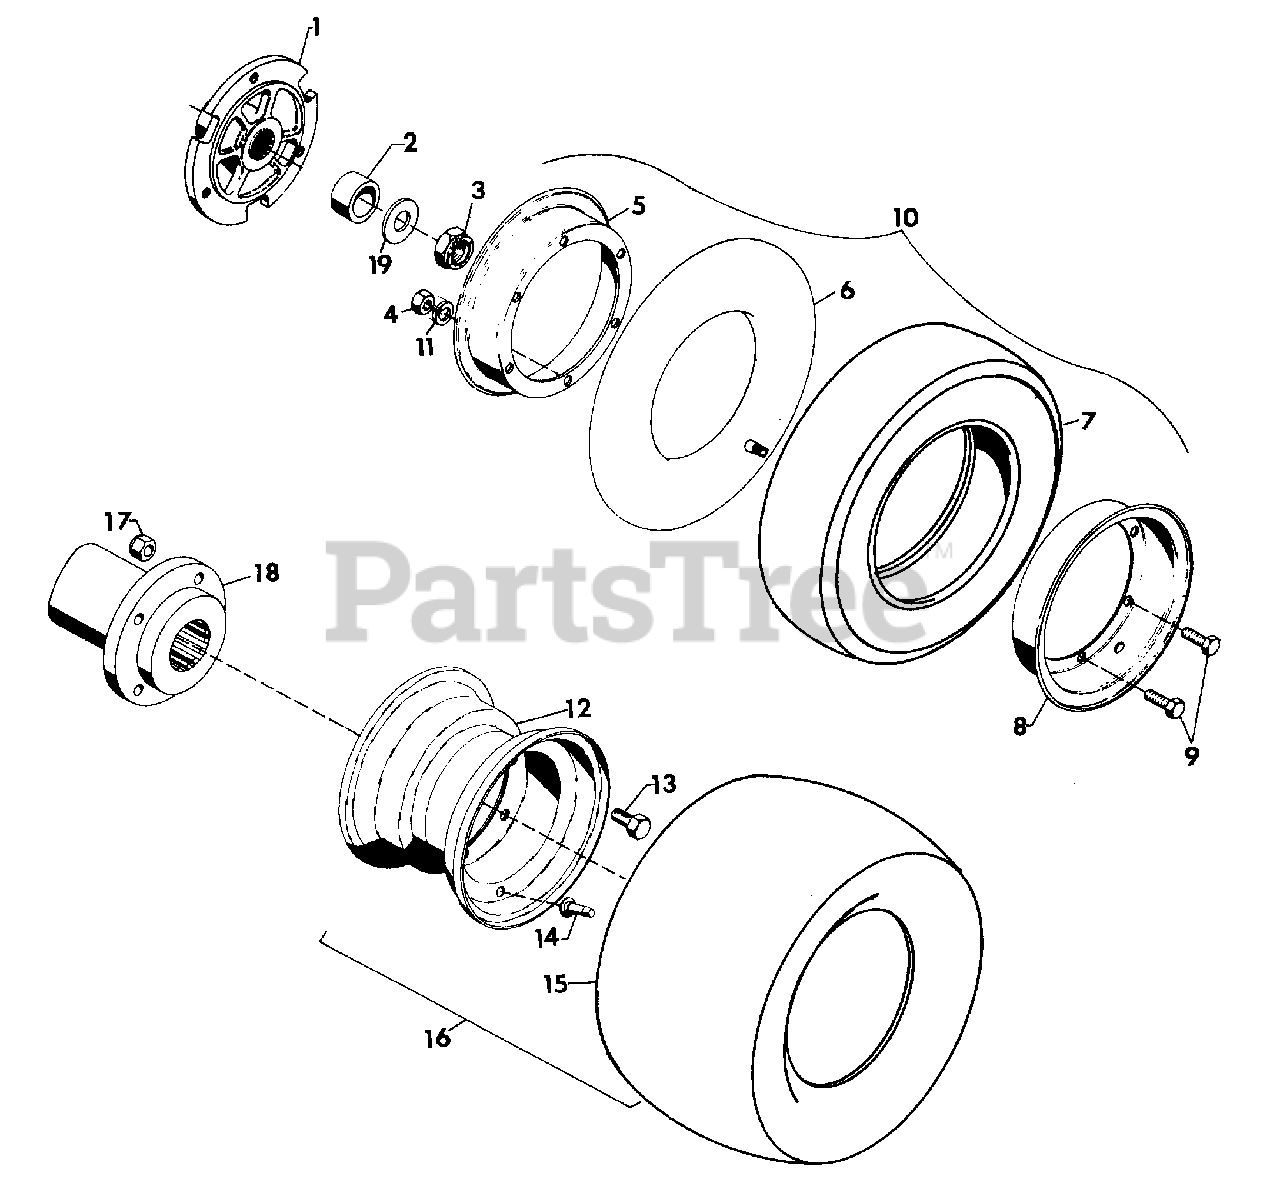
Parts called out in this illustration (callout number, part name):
1	HUB, WHEEL
2	SPACER
3	NUT, 3/4-10 LIGHT THIN HEX
4	NUT, JAM; 3/8-16 HEX
5	DISC, INNER, WHEEL
6	TUBE
7	TIRE, TRACTOR; DIAMOND TREAD 4.80 X 4.00-8
8	DISC, WHEEL
9	BOLT, HEX; 3/8-16 X 5/8
10	ASSEMBLY, SUPER GRIP WHEEL 4.00-8
11	WASHER, LOCK; 3/8 SP
12	RIM, 18 X 8.50-8
13	BOLT, HEX; 1/2-13 X 1.25
14	ASSEMBLY, VALVE STEM
15	TIRE 18 X 8.50-8
16	ASSEMBLY, WHEEL; 18 X 8.50 X 8
17	NUT, LOCK; 1/2-13 WASHER INSERT
18	HUB, FOR 18 X 8.50 X 8 WHEEL ASM.
19	WASHER, FLAT; .812 X 1.469 X .134
